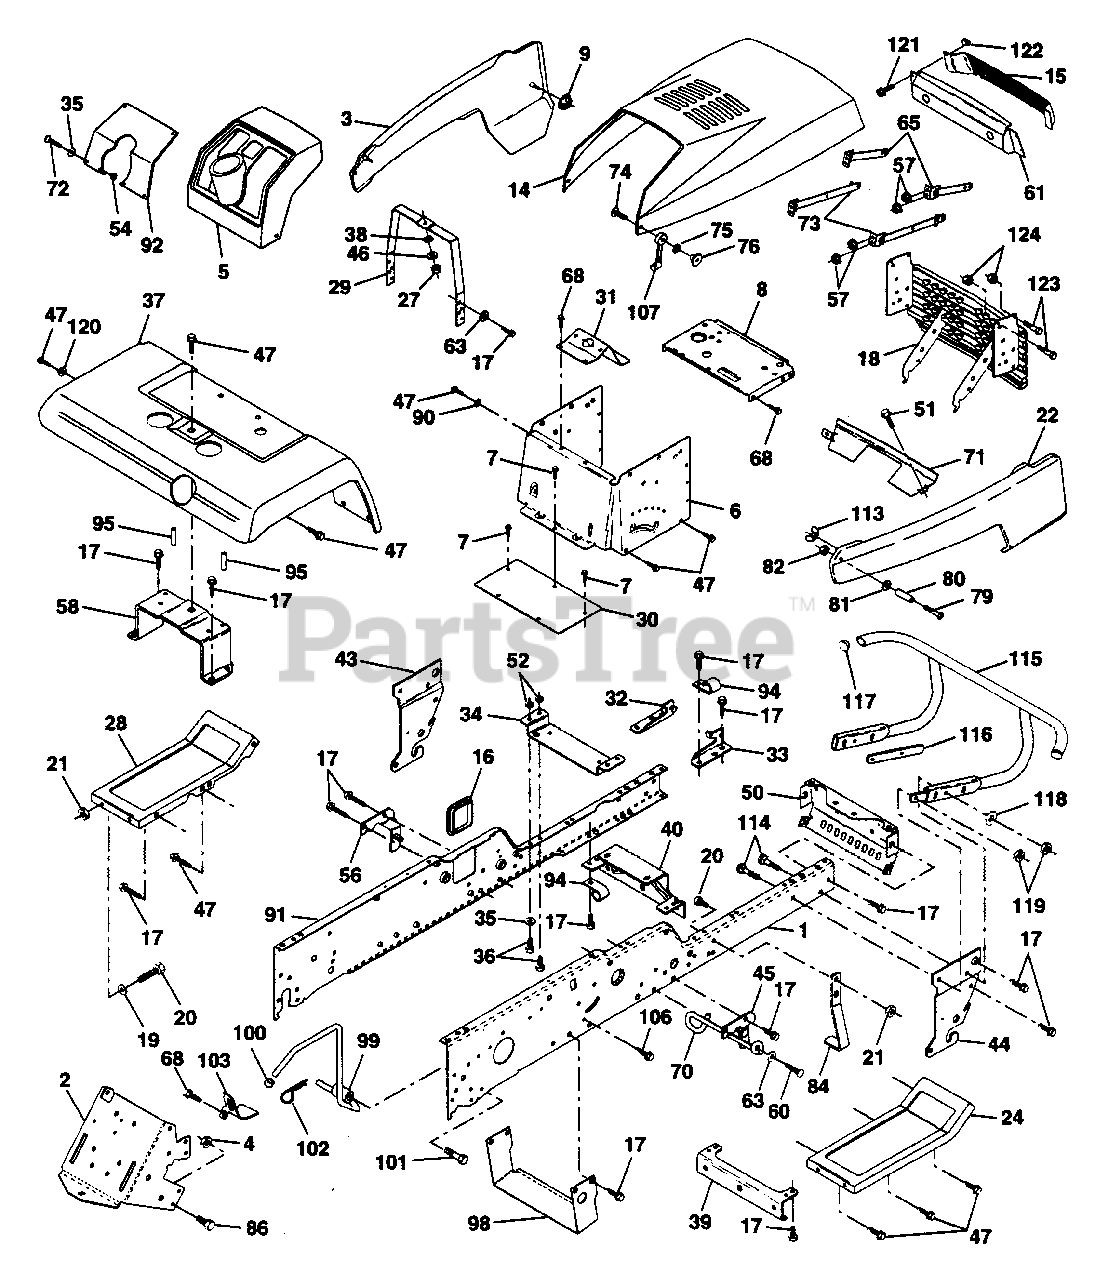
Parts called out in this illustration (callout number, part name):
1	Rail, Frame RH
2	Drawbar, Gt
3	Panel Asm., Side LH
4	Nut, Lock Hex 7/16 Unc
5	Dash, Plastic Black
6	Dash, 1PCS, Lower
7	Screw, Thd Cut 1/4-20 x 1/2
8	Support, Battery
9	Nut, Pal
14	Hood Asm., Pnt
15	Lens, Headlight Bar
16	Cover, Access
17	Screw, Thdrol 3/8-16 x 3/4
19	Washer 13/32 x 13/16 x 12 Ga.
20	Bolt, Fin Hex 3/8-16 x 1
21	Nut, Crownlock 3/8-16
22	Panel Asm., Side RH
27	Nut, Fin Hex 1/4-20
29	Bracket, Support Dash
31	Bracket, Support Steering
32	Bracket Asm., Frame Pivot Lh
33	Bracket Asm., Frame Pivot Rh
34	Bracket, Engine Support Rear
35	Washer 11/32 x 11/16 x 16 Ga.
36	Bolt, Fin Hex 5/16-18 x 3/4
38	Washer, Lock 1/4
39	Bracket, Axle Front
40	Bracket, Support Axle/Engine
43	Bracket, Spnsn Front Lh
44	Bracket, Spnsn Front Rh
45	Bracket Asm., Susp Chassis Rh
46	Washer 9/32 x 3/4 x 16 Ga.
47	Screw Thdrol 3/8-16 x 1/2
50	Bracket, Chassis Front
51	Screw Tap Tite 1/4-20 x 1/2
52	Nut, Crownlock 5/16-18
54	Nut 5/16-18
56	Bracket Asm., Susp Chassis Lh
57	Nut Keps Hex 1/4-20
58	Bracket Asm., Fender
60	Screw Thdrol 3/8-16 x 1-1/4
61	Beze. Asem.
63	Washer 13/32 x 1 x 14 Ga.
65	Strap, Asm. Hinge Front
68	Screw, Thdrol 5/16-18 x 1/2
70	Guide, Belt Mid Span
71	Strap, Grille
72	Screw, Mach Trhd 5/16-18 x 3/4
73	Strap, Asm. Hinge Rear
74	Screw, Machine #10-24
75	Washer, Lock #10
76	Nut, Weld #10-24
79	Screw, Machine #10-24 x 1/4
80	Spacer, Split
81	Washer 7/32 x 1/2 x 18 Ga.
82	Nut #10-24
84	Stop, Over Center Mower
86	Bolt, Fin Hex 7/16-14 Unc x 1
90	Washer, Lock External Tooth 3/8
91	Rail, Frame Lh
92	Plate, Silkscreen Dash
94	Clip, Fuel Line
95	Push Nut, Nylon
98	Bracket Chassis Skid
99	Rod Asm. Bypass
100	Cap Brake Parking Red
101	Screw Thdrol. 3/8-16 x 1-3/4
102	Retainer Spring 1"
103	Bracket Lock Bypass
106	Screw Thdrol Hex Head Zinc
107	Latch, Chute Blk
113	Nut, Plastic Locking Wing 1/4-20
114	Bolt, Carriage 3/8-16 x 1-1/4
116	Bracket Extension Bumper
117	Plug, Plastic
118	Washer 13/32 x 13/16 x 16 Ga.
119	Nut, Crownlock 3/8-16 UNC
120	Washer 13/32 x 1 x 16 Ga.
121	Screw Hex Whd Tap #10-16 x 5/8
123	Bolt Shoulder 1/4-20
124	Nut Crownlock 1/4-20
